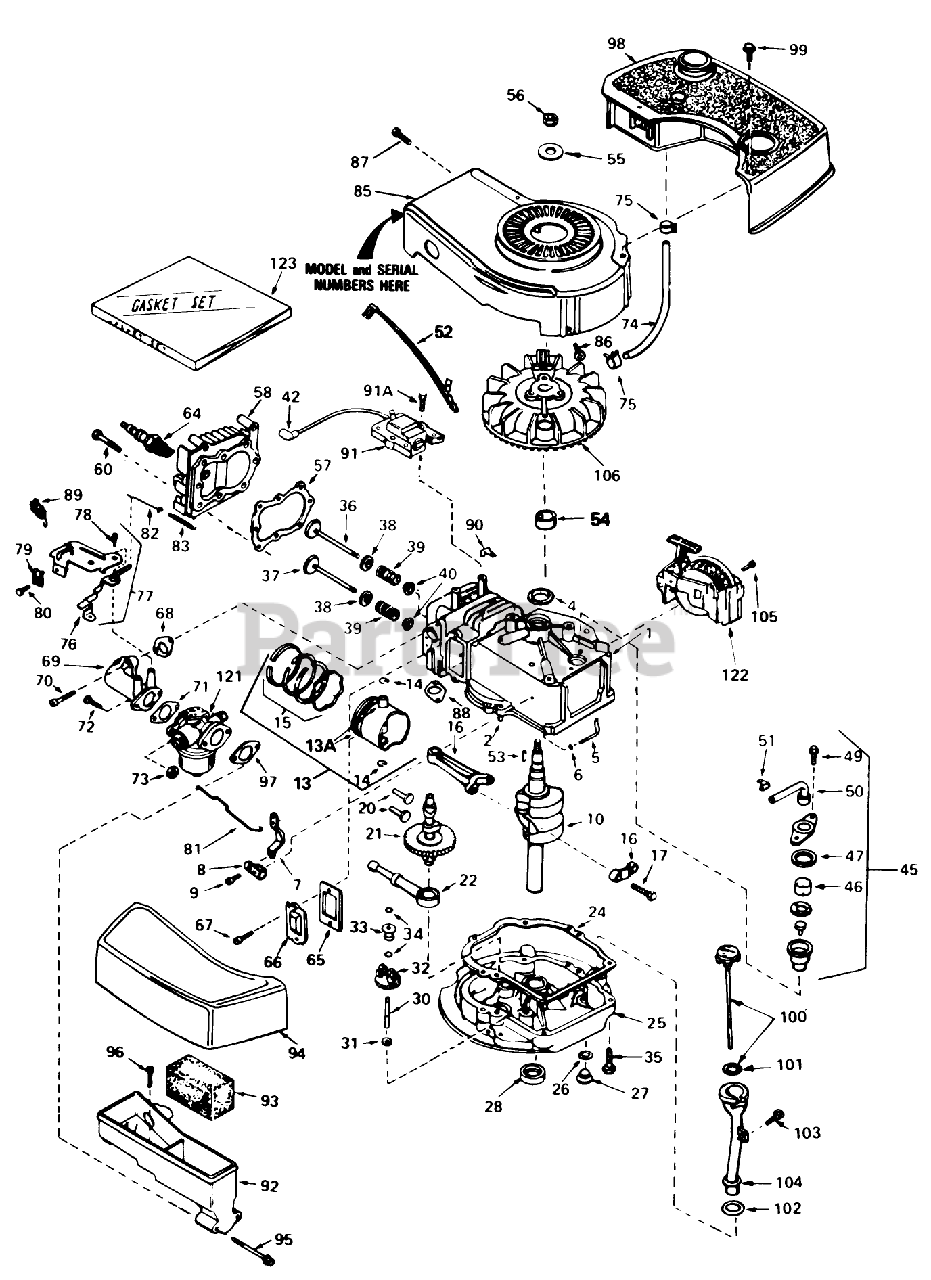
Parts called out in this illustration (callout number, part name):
1	Cyiinder Assy. (Incl. Ref. #2, 4 105)
2	Pin-Dowel
4	Seal-Oil
5	Rod, Governor (Incl. No. 36)
6	Washer-Flat
7	Governor Lever
8	Clamp-Lever, Governor
9	Screw
10	Crankshaft
13	Piston, Pin Ring Assy. (Std.) (Incl. Ref. #13A, 14 15)
13	Piston, Pin Ring Assy. (.010 oversize) (Incl. Ref. #13A, 14 15)
13	Piston, Pin Ring Assy. (.020 oversize) (Incl. Ref. #13A, 14 15)
13A	Piston Pin Assy. (Incl . Ref. . #14) (Std.)
13A	Piston Pin Assy. (Incl. Ref. #14) (.010 Oversize)
13A	Piston Pin Assy. (.020 oversize) (Incl. Ref. #14)
14	Ring-Retaining, Piston Pin
15	Ring Set (Std.)
15	Ring Set (.020" OS)
15	Ring Set (.010" OS)
16	Rod Assy., Connecting (Incl. Ref. #17)
17	Bolt-Rod, Connecting
20	Lifter-Valve
21	Camshaft(Mech.Comp. Release)
22	Oil Pump ASM
24	Gasket, Mounting
25	Flange Assy., Mounting (Incl. Ref. #26thru 30)
26	Gasket-Oil Drain
27	Plug Oil Drain
28	Seal Oil
30	Shaft-Governor
31	Washer-Flat
32	Governor Gear ASM
33	Spool-Governor
34	Ring-Retaining
35	Screw (1/4-20 x 1-1/4)
36	Valve, Intake (Std.) (Incl. Ref. #40)
36	Valve, Intake (1/32" oversize)(Incl. No. 40)
37	Valve, Exhaust (Std.)(Incl. No. 40)
37	Valve, Intake (1/32" oversize)(Incl. No. 40)
38	Cap-Upper Valve Spring
39	Spring-Valve
40	Cap-Valve, Spring
42	Cover-Spark Plug
45	Breather Assy. (Incl. Ref. #46 thru 51)
46	Element-Breather
47	Gasket-Breather
49	Screw (10-24 x 9/16)
50	Tube, Breaker
51	Clip, Breather
52	Wire-Ground
53	Key-Flywheel
54	Spacer
55	Washer-Belleville
56	Nut-Flywheel
57	63573 GIL 42 SNWTHW
58	Head-Cylinder
60	Screw (5/16-18x1-1/2)
64	Plug, Spark (J17LM or equiv.)
64	Plug, Spark (Champion RCJ-8)
65	Gasket-Breather
66	Cover-Valve
67	Screw
68	Gasket-Intake
69	Pipe, Intake (Incl. No. 68)
70	Screw (1/4-20 x 1)
71	Gasket-Carburetor
73	Nut and Lock Washer (1/4-28)
74	Line-Fuel
75	Clamp-Line, Fuel
76	Lever Control
77	Control Assy., Speed (Incl. Nos, 76, 78 89)
78	Screw, Hex Washer Hd Shoulder Self-Tap
79	Conduit
80	Screw (10-32 x 3/8)
81	Link-Throttle
82	Link Governor Spring
83	Spring Governor
85	Housing-Blower
86	Screw (1/4-20x19/32)
87	Screw (10-24 x 9/16)
88	Gasket Exhaust
89	Terminal
90	Clip-Wire
91	Solid State
91A	Screw
92	Body Air Cleaner
93	Filer, Air
94	Cove, Air Cleaner
95	Screw Fil Hd.
96	Screw, Hex Hd.
97	Gasket-Air Cleaner
98	Tank-Fuel
99	Screw (10-32 x 35/64)
100	Dipstick, Oil (Incl. Ref. #101)(Twist Lock)
101	O-Ring
102	Gasket
103	Screw (10-32 x 1/2)
104	Tube-Oil Fill
105	Screw (1/2-20x5/8)
106	Flywheel
121	Carburetor (Incl. Ref. #71)
122	Starter-Sidemount
123	Gasket Set
